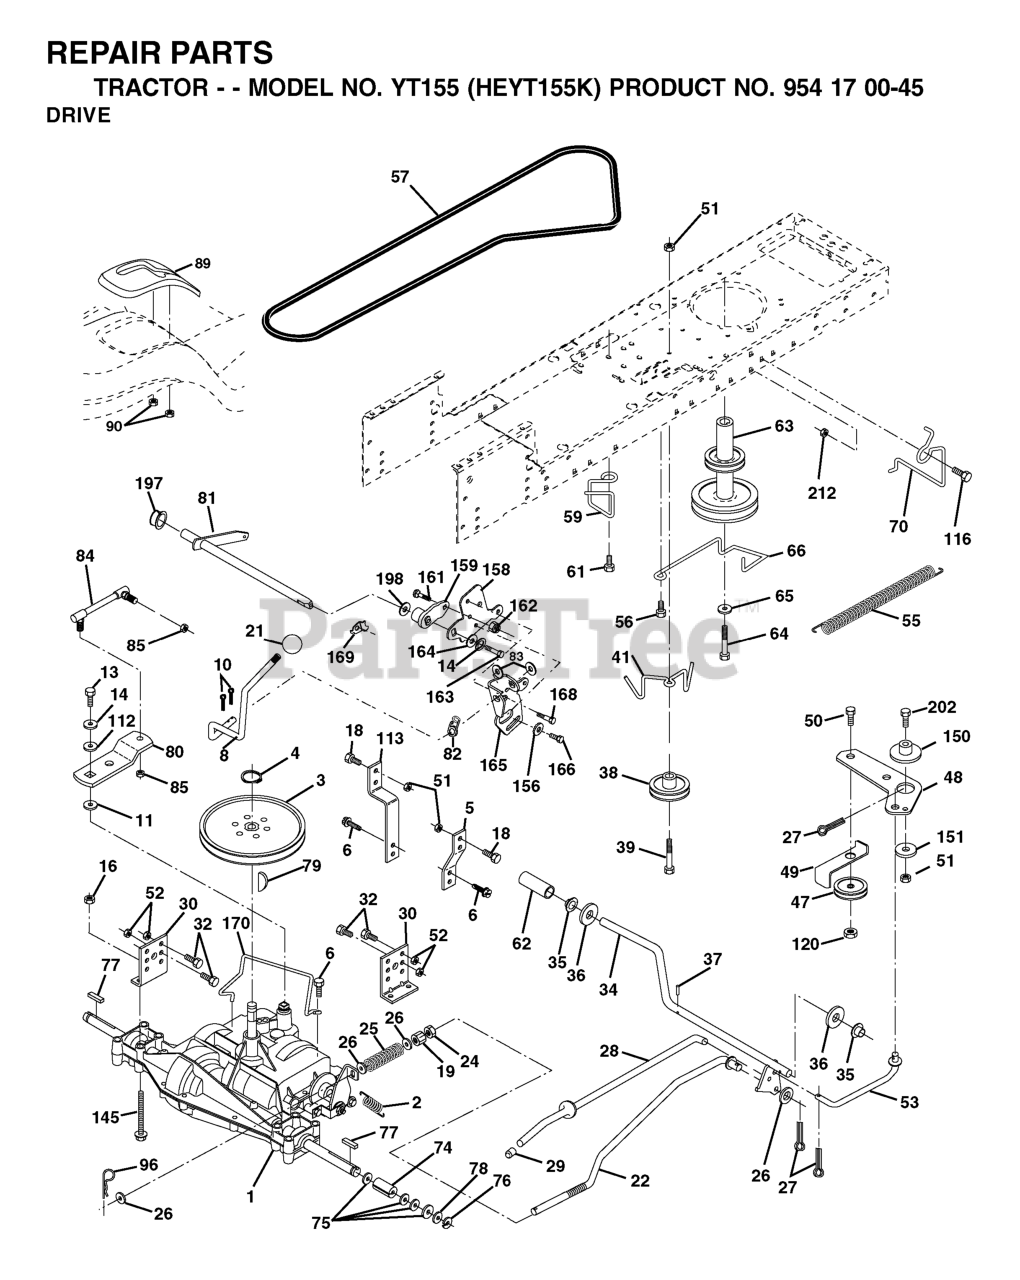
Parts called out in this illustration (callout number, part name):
2	SPRING,BRAKE RETURN
3	PULLEY TRANS
4	RETAINING RING LT
5	STRAP TORQUE
6	SCREW 5/16"
8	ROD SHIFT FENDER ADJUST STLT
10	PIN COTTER
11	WASH-SHFT PLT LT
13	BOLT 1/4-28X3/4
14	LOCKWASHER
16	NUT.71038.31-18.HEX.NYLOCK
19	NUT
21	KNOB.DUCKHEAD.1/2
24	NUT
25	SPRING ROD LT
26	WASHER
27	COTTER PIN
28	ROD, PARKING BRAKE
29	PLUNGER CAP
30	BRKT, TRNSXLE MNT 20"
32	BOLT
34	SHAFT, FOOT PEDAL
35	BEARING.NYLON
37	DRIVE PIN
38	PULLEY IDLER COMPOSITE
39	BOLT
41	KEEPER, BELT IDLER
47	IDLER PULLEY
48	BELLCRANK, CLUTCH
49	RETAIN BELT
50	BOLT
52	LOCKNUT
53	LINK, CLUTCH LT
55	SPRING, RETURN LT
56	SCREW.3/8-16
57	V-BELT
59	KEEPER, BELT CENTER
61	SCREW 3/8-16X.875
62	COVER, PEDAL (1 2)
63	ENGINE PULLEY
64	BOLT
65	LOCKWASHER
66	KEEPER BELT ENGINE
70	KEEPER BELT ENG
74	SPACER AXLE
77	SQUARE KEY
79	KEY STD (1373) DANA
81	SHAFT ASM CROSS TAPERED PMST/2
82	SHIFT SPRING
83	WASHER
84	LINK.TRANSAXLE.PMST/DANA.20"
85	NUT LOCK CENTER 1/4 -28 FNTHD
90	NUT.PUSH.3/16
96	RETAINER M
113	STRAP TORQUE LH LT
116	BOLT D
120	NUT LOCK FLG 3/8-16 UNC
150	SPACER, RETAINER
151	WASHER 12/32X2X10GA
156	WASHER.SRRTD.5/16
158	BRACKET
159	HUB
161	BOLT
162	NUT.CROWNLOCK.1/4
164	Washer 5/8 x .281 x 10 Ga.
165	RP BRACKET
168	BOLT.SHOULDER.5/16-18X
169	PLATE.FASTENING.CROSS.SHAFT
170	KEEPER BELT T/A
197	NYLINER SNAP 5/8" ID
198	WASHER.NYL.7/8IDX.105"HYD CR
212	NUT
